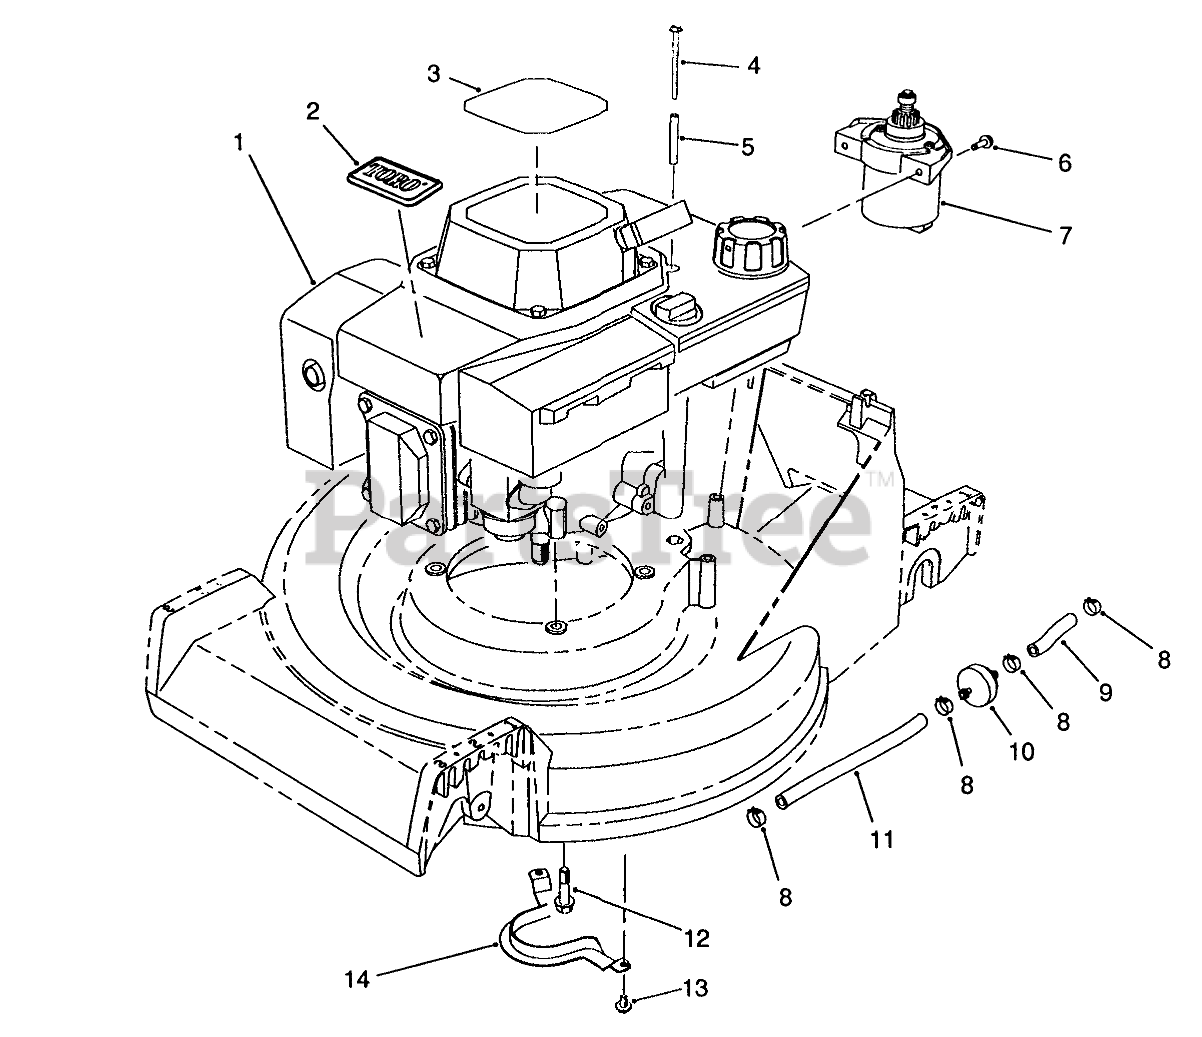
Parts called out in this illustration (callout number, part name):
1	ENGINE ASSY OHV BBC/K
2	TORO LOGO PLT
3	DECAL-HV INT'L
4	THRD FORMING SCREW
5	TUBULAR SPACER
6	SCREW
7	STARTER MOTOR ASM
8	CLAMP-FUEL LINE
9	LINE-GAS
10	FILTER-FUEL
11	HOSE-FUEL
12	SCREW-HWH
13	SCREW-HWHTF
14	Guide-Belt
